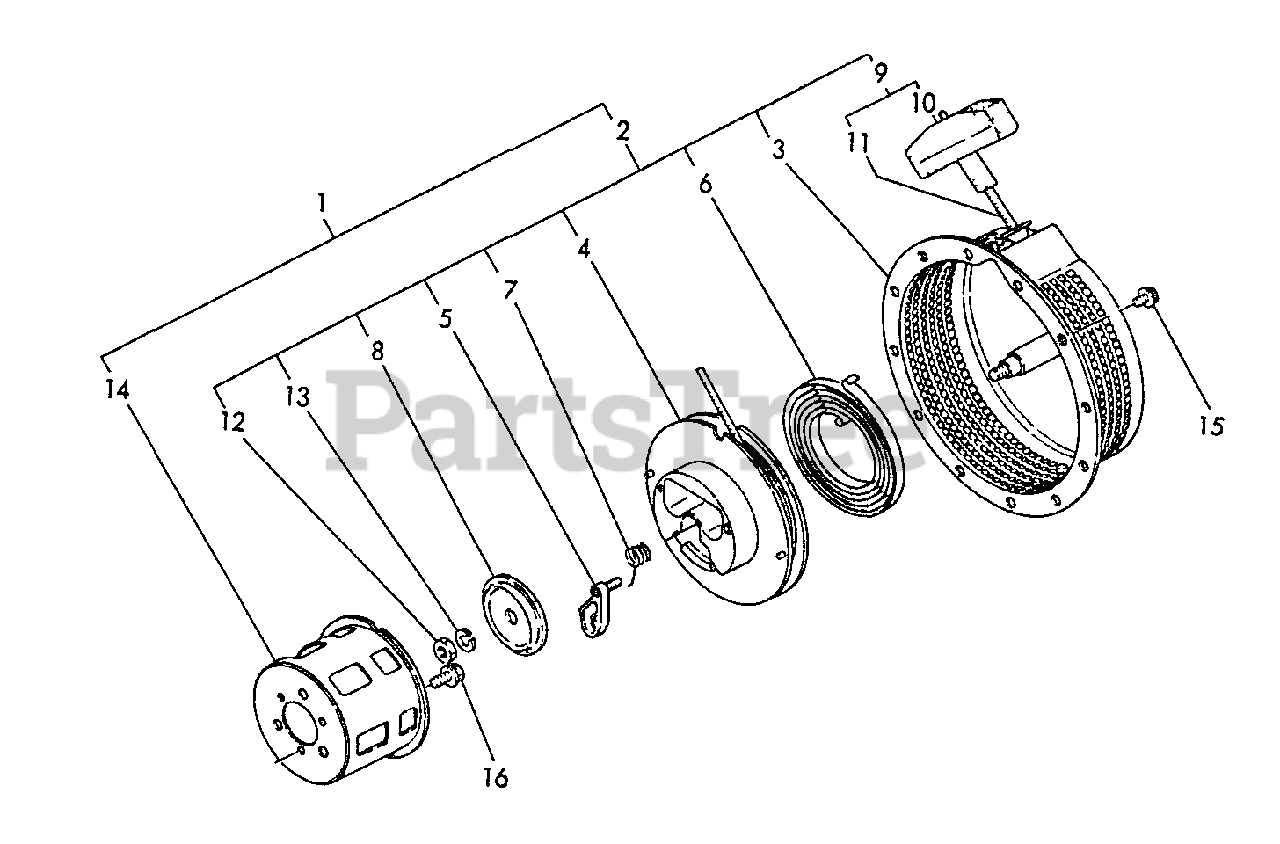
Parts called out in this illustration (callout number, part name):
1	STARTER ASSY
2	RECOIL ASSY
3	CASE, STARTER
4	PULLEY
5	RATCHET
7	SPRING, FRICTION
8	PLATE
9	ROPE ASSY
10	GRIP, STARTER
11	STARTER WIRE
12	NUT
13	LOCKWASHER
14	PULLEY, STARTER
15	BOLT - 6×8 -- PLATED
16	BOLT - 6×12 -- PLATED
